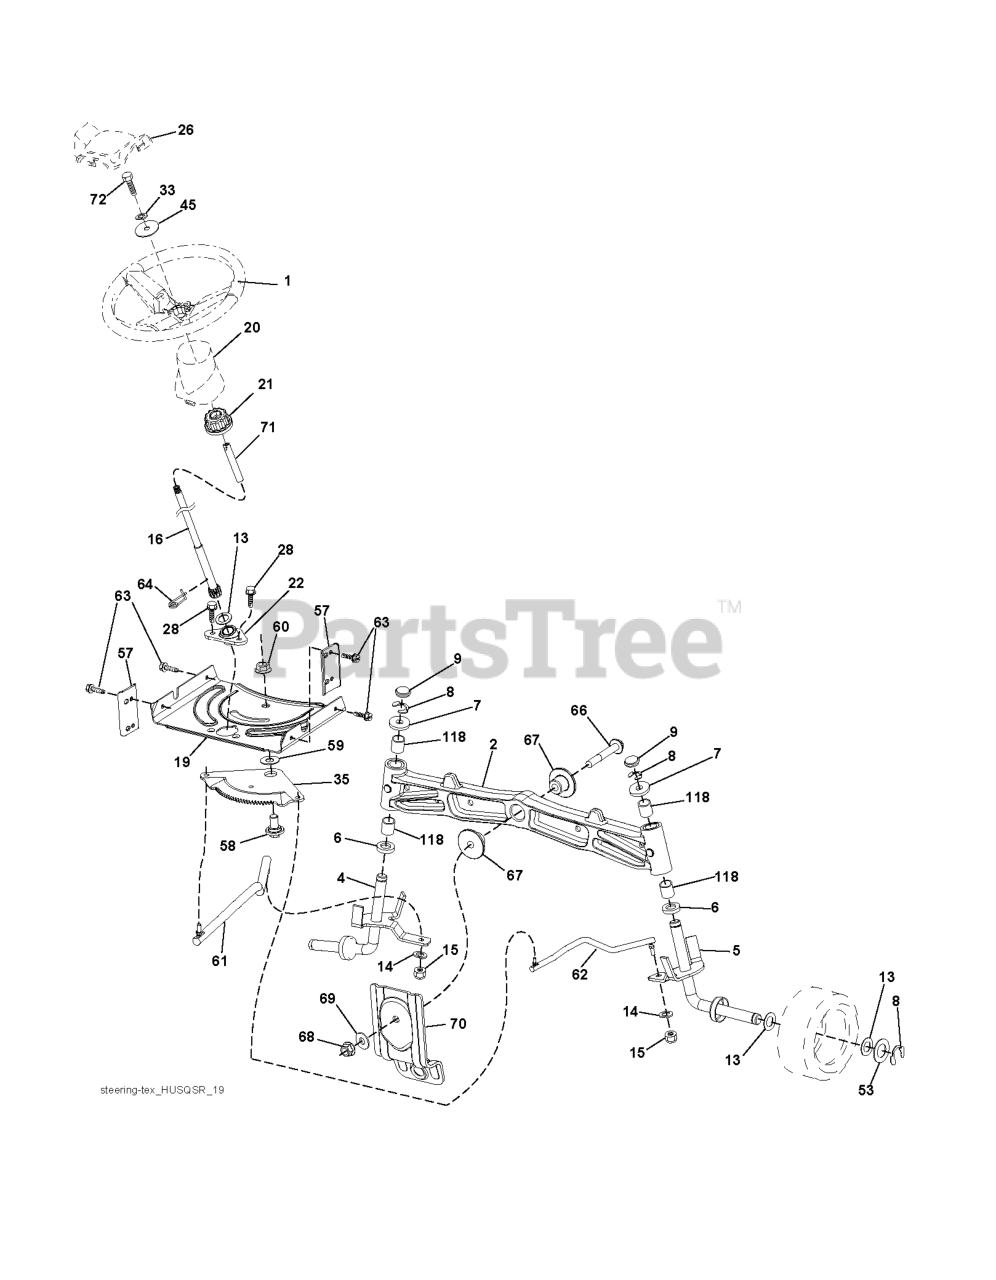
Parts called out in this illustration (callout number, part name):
1	RP WHEEL.STEER.HUSQ.PREM.OVMLD
2	AXLE.SVC.ASM CAST IRON.TEX
4	SPINDLE.WELDED.LH.15"TEX
5	SPINDLE.WELDED.RH.15"T
6	THRUST WASHER
9	CAP.SPINDLE.BLACK
14	WASHER, LOCK 3/8
15	NUT CROWNLOCK 3/8-24
16	SHAFT.STEER.3/4.PLATED.TEX
19	PLATE.STEER.DDL.NLT/NG
20	BOOT, STEERING
21	ADAPTER, WHEEL STNG..
22	STEERING.SUPT.LOWER.
26	RP INSERT.CAP.WHL.STRG.HUSQ.
28	SCREW, 3/8-16X3/4
33	WASHER.LOCK.HVY.HLCL.SPR.5/16
35	GEAR.SECTOR.PLATE.DDL.
45	WASHER.11/32
53	WASHER.HARDENED
57	BRACKET.UPSTOP.TEX
58	BOLT.SHOULDER.SECTOR.P
59	WASHER.THURST.SECTOR.S
60	NUT FLANGE LOCK 5/8-11
61	DRAGLINK.LH.BALLSTUD.D
62	DRAGLINK.RH.BALLSTUD.D
63	SCREW
64	RETAINER.CLIP.SPRING.S
66	BOLT HEX FGHD 7/16-14 X 3 SERR
67	BUSHING.PM.FRONT AXLE
68	NUT.LOCK.FLANGE.7/16
69	WASHER.1.5X.505X.118
70	BRKT.DECK.SUSPENSION.F
71	SHAFT.EXTEN.STRG.SPLINE
72	BOLT 5/16-18 X 4 W/PATCH
118	BUSHING, AXLE CAST
